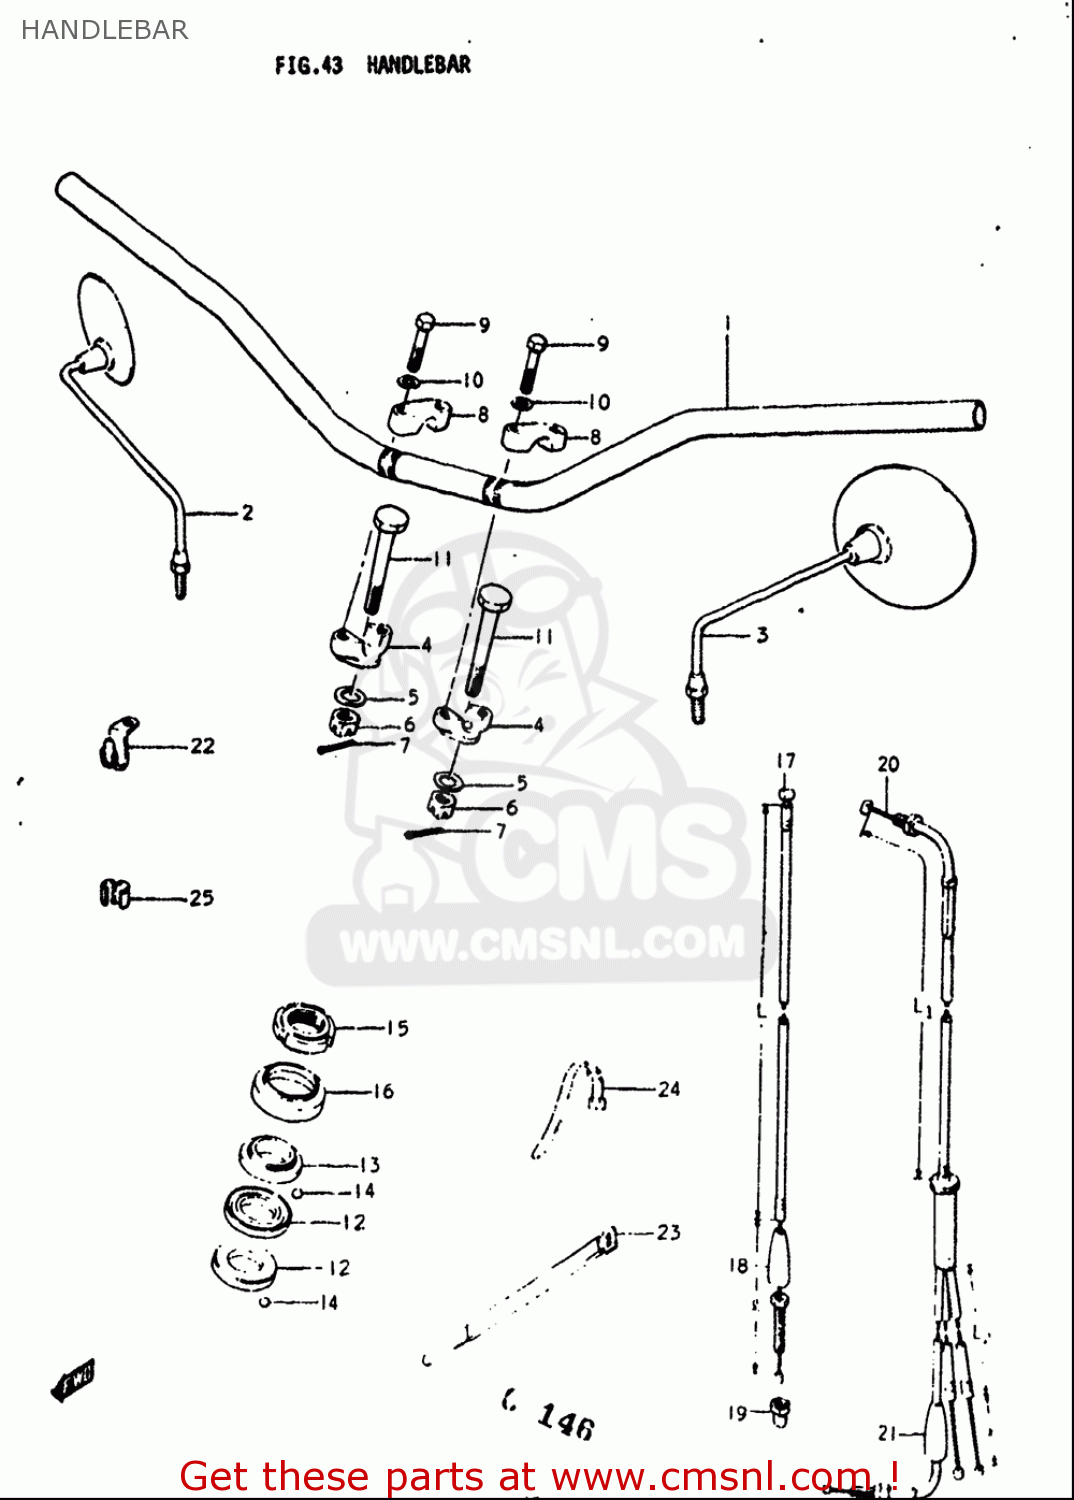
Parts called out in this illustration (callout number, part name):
1	HANDLEBAR
2	MIRROR ASSY,RE
3	MIRROR ASSY,LEFT
4	HOLDER,HANDLEBAR LWR
5	WASHER(10.5X28X2.3)
6	NUT
7	PIN, COTTER
8	HOLDER,HANDLE UPR
9	BOLT
10	WASHER,LOCK
12	LACE,STEERING INNER LWR
13	LACE,STEERING OUTER UPR
14	BALL
15	NUT,STEERING STEM(25X44X10)
16	DUST SEAL,STEERING UPR
17	CABLE,CLUTCH
19	NUT
20	CABLE ASSY,THROTTLE
21	SEAL,DUST(7X18X30)
23	CLAMP
24	CLAMP(L:120)
25	CLIP
